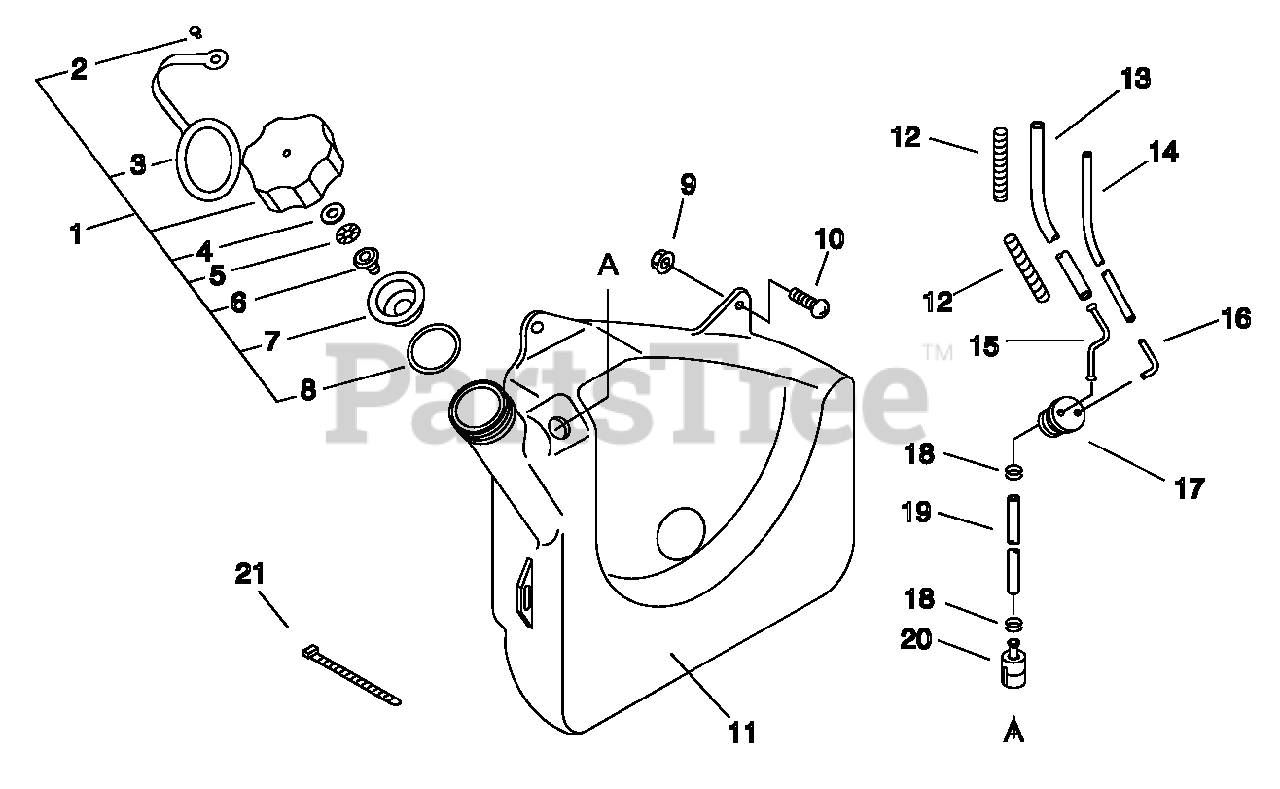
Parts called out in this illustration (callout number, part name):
1	CAP ASSY
3	CONNECTOR, CAP
4	WASHER - 3
7	VENT HOLDER ASSY
8	GASKET, CAP
9	NUT - 5 -- FLANGE
10	SCREW - 5X20
11	TANK, FUEL
12	TUBE
13	PIPE, FUEL - 3X7X465
14	PIPE - 2X4X470 -- CLEAR
15	CONNECTOR, PIPE
16	CONNECTOR, PIPE
17	GROMMET
18	CLIP - 6.5
19	PIPE - 3X6X280 -- BLACK
20	FILTER, FUEL
21	TIE, CABLE - SMALL
